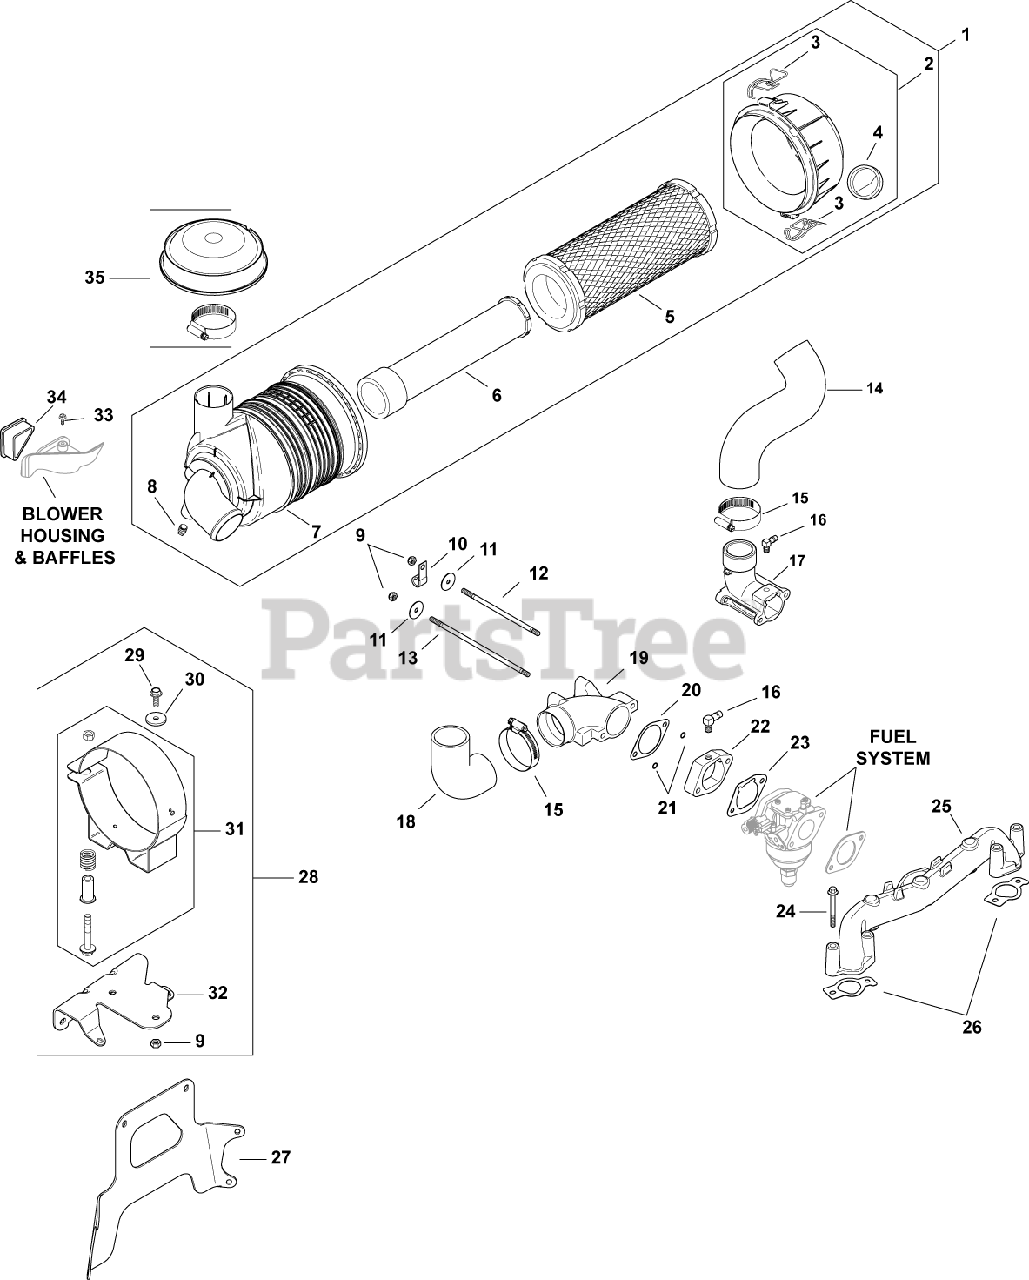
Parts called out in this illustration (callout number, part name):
1	AIR CLNR, CANISTER-USE 25 048 17-S
2	COVER ASSEMBLY, AIR CLEANER
3	CLIP - USE 62 154 07-S
4	VALVE, DUST EJECTOR
5	ELEMENT, AIR FILTER - PRIMARY
6	ELEMENT, AIR FILTER - SAFETY
7	HOUSING, HD AIR CLEANER
8	PLUG, PIPE
9	NUT, LOCK M6X1.0
10	CLIP, CABLE
11	WASHER
12	STUD, M6X1.0X140
13	STUD, M6X1.0X180
14	HOSE, AIR CLEANER
15	CLAMP, HOSE
16	CONNECTOR, HOSE
17	ELBOW, AIR CLEANER
18	HOSE, AIR CLEANER
19	ADAPTER, ELBOW
20	GASKET, AIR CLEANER ADAPTER
21	O-RING
22	ADAPTER, REMOTE A/C-USE 24 029 87-S
23	GASKET, AIR CLEANER BASE
24	SCREW, FLG M6X1.0X55
25	MANIFOLD, INTAKE
26	GASKET, INTAKE MANIFOLD USE 24 041 79-S
27	BRACKET, MAIN SUPPORT-USE 24 126 185-S
28	BRACKET, AIR CLEANER -USE 24 126 186-S
29	SCREW, FLG M6X1.0X16
30	WASHER, FLAT 1/4" (O.D. 1")
31	BRACKET, AIR CLEANER-USE 24 126 191-S
32	BRACKET, AIR CLEANER-USE 24 126 184-S
33	SCREW, WSH HD TAP #8-18X1/2"
34	COVER, BLOWER HOUSING USE 24 096 160-S
35	HOOD, AIR CLEANER (5.25)-USE 25 324 04-S
2407210-S	STUD, M6X1.0X180
